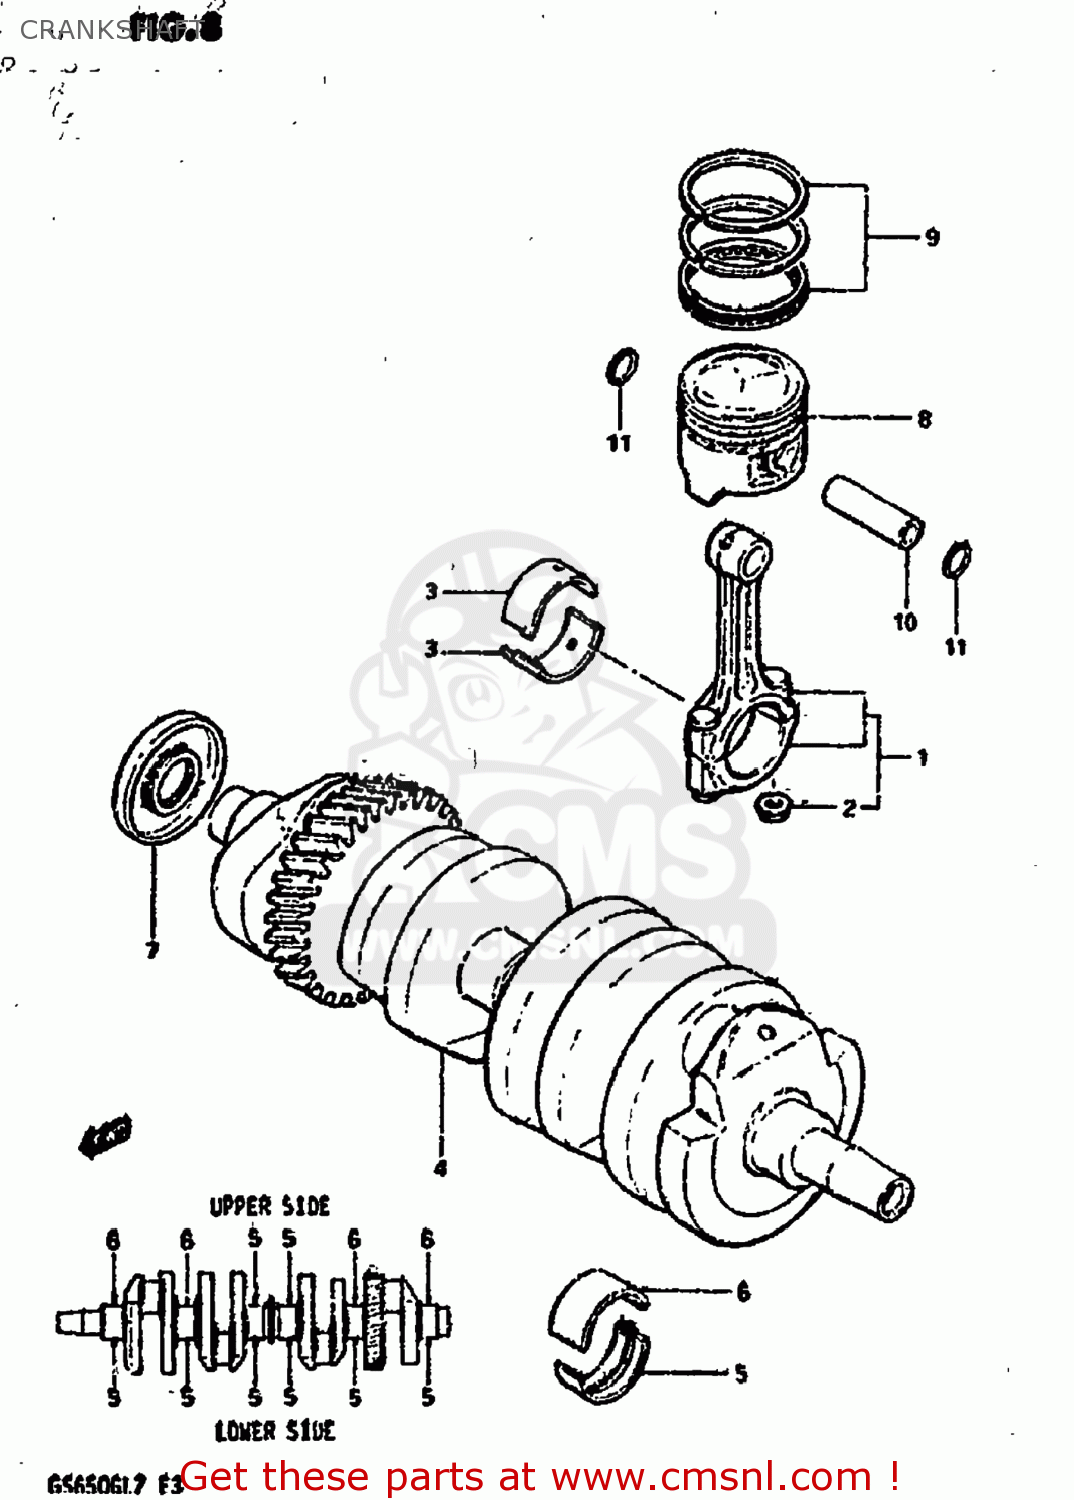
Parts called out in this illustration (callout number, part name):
1	ROD ASSEMBLY,CONNECTING
2	NUT
3	BEARING,CRANK PIN
4	CRANKSHAFT
5	METAL CRANKSHAFT
6	METAL CRANKSHAFT
7	OIL SEAL
8	PISTON
9	RING SET,PISTON
10	PIN,PISTON
11	CIRCLIP
